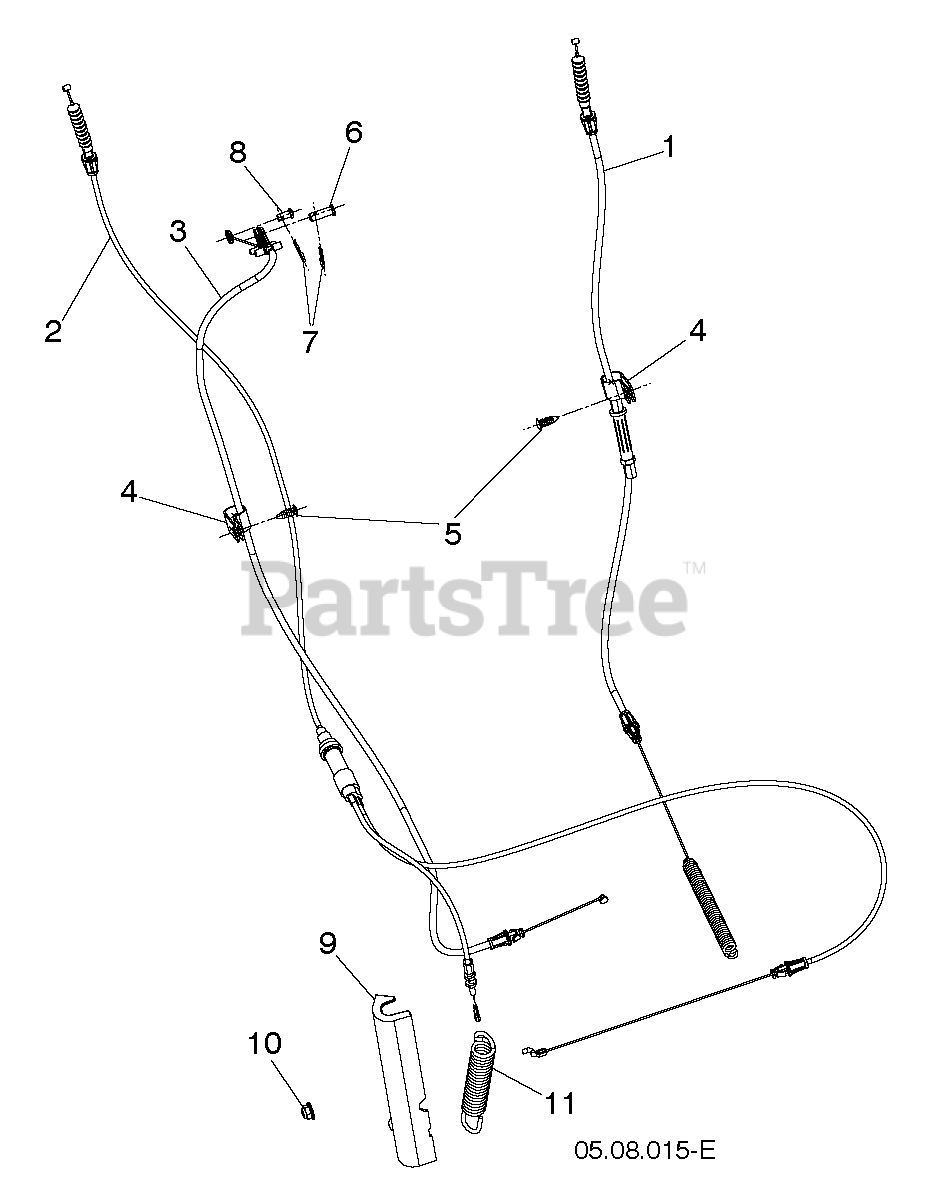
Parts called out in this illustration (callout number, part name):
1	Cables
2	CABLE IMPELLER
3	CABLE.CONTROL.SPEED.DSST.OPP
4	CLIP.CABLE.BLK
5	FASTENER.PUSH.O.250X0.783
6	PIN CLEVIS 5/16X.875
7	HAIRPIN.SOFT.ZINC.059X1.125
8	PIN CLEVIS .25 X .31
9	COVER AUGER CABLE
10	NUT HEXAGON FLANGE 5/16-18 ST
11	SPRING EXTENSION; AUGER EXTENS
